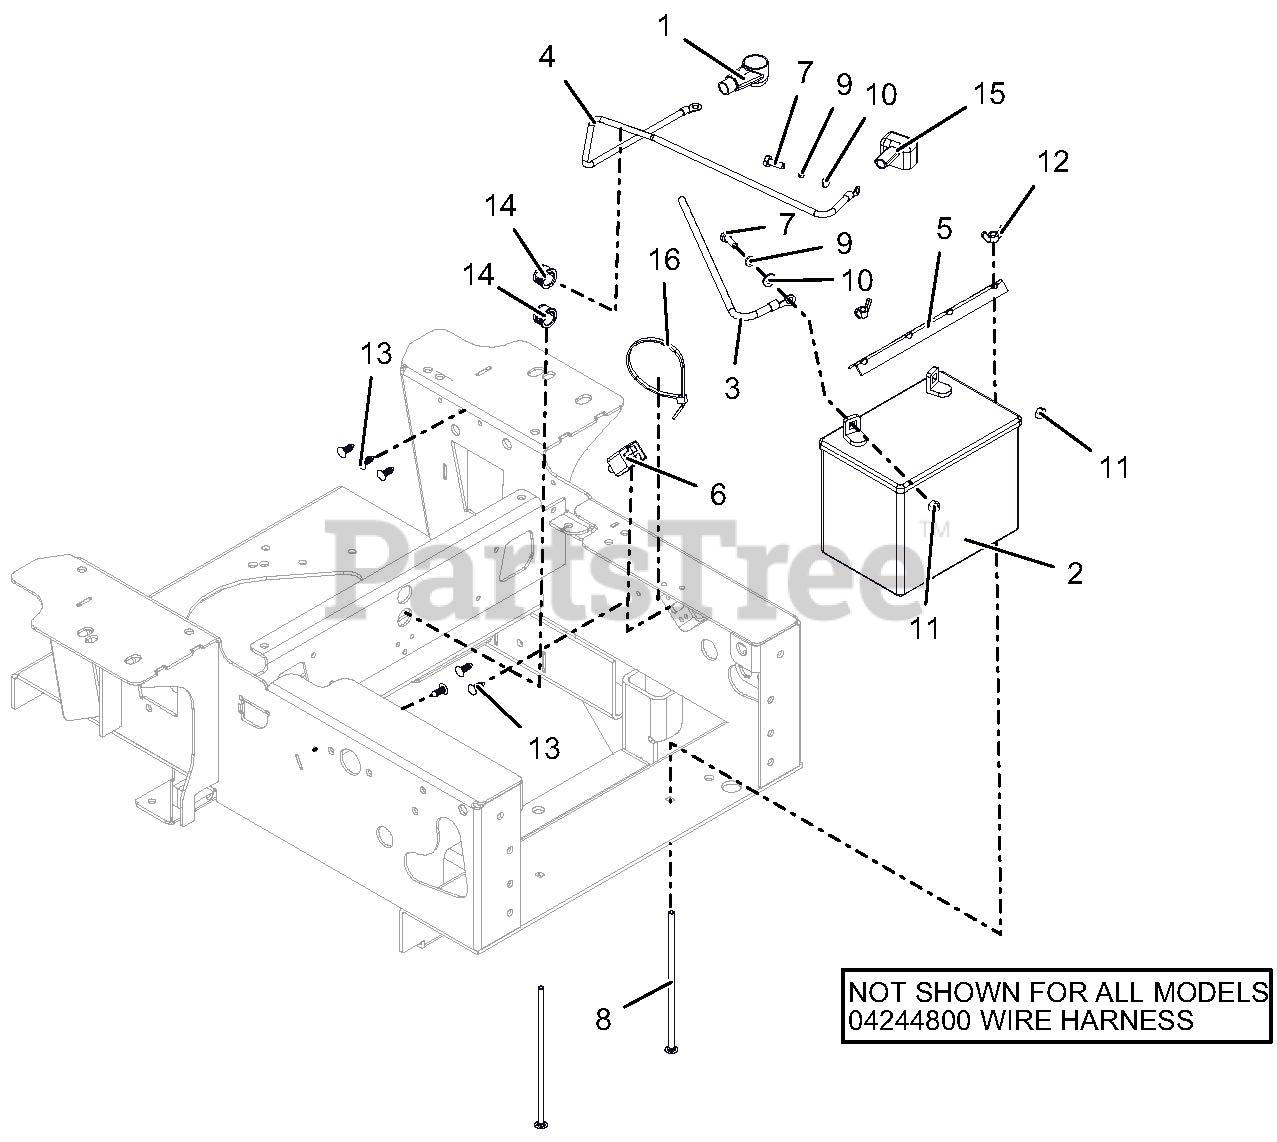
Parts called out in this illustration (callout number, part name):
1	BOOT, BATTERY TERMINAL-RED
2	BATTERY, 300 CCA 10U1L
3	CABLE, GROUND 22.00"
4	CABLE, STARTER .31 X 23.00 X .31
5	HOLD DOWN - BLK
6	SWITCH, SNAP IN -N.O./N.O
7	BLT-HEX .25-20X.75 GR5 YWZC
8	BLT-RDHDSQNK .25-20X7.50 G2 YWZC
9	WSHR-LK .25X.062 REG YWZC
10	WSHR-FL-STL.281X.62X.065 YWZC
11	NUT-HEX .25-20 YWZC
12	NUT-LOCKING WING 1/4-20
13	RIVET, .25 NYLON PANEL
14	BUSH, PANEL SNAP .687X.875X.56
15	INSULATOR
16	CABLE, TIE 5.50 LG
